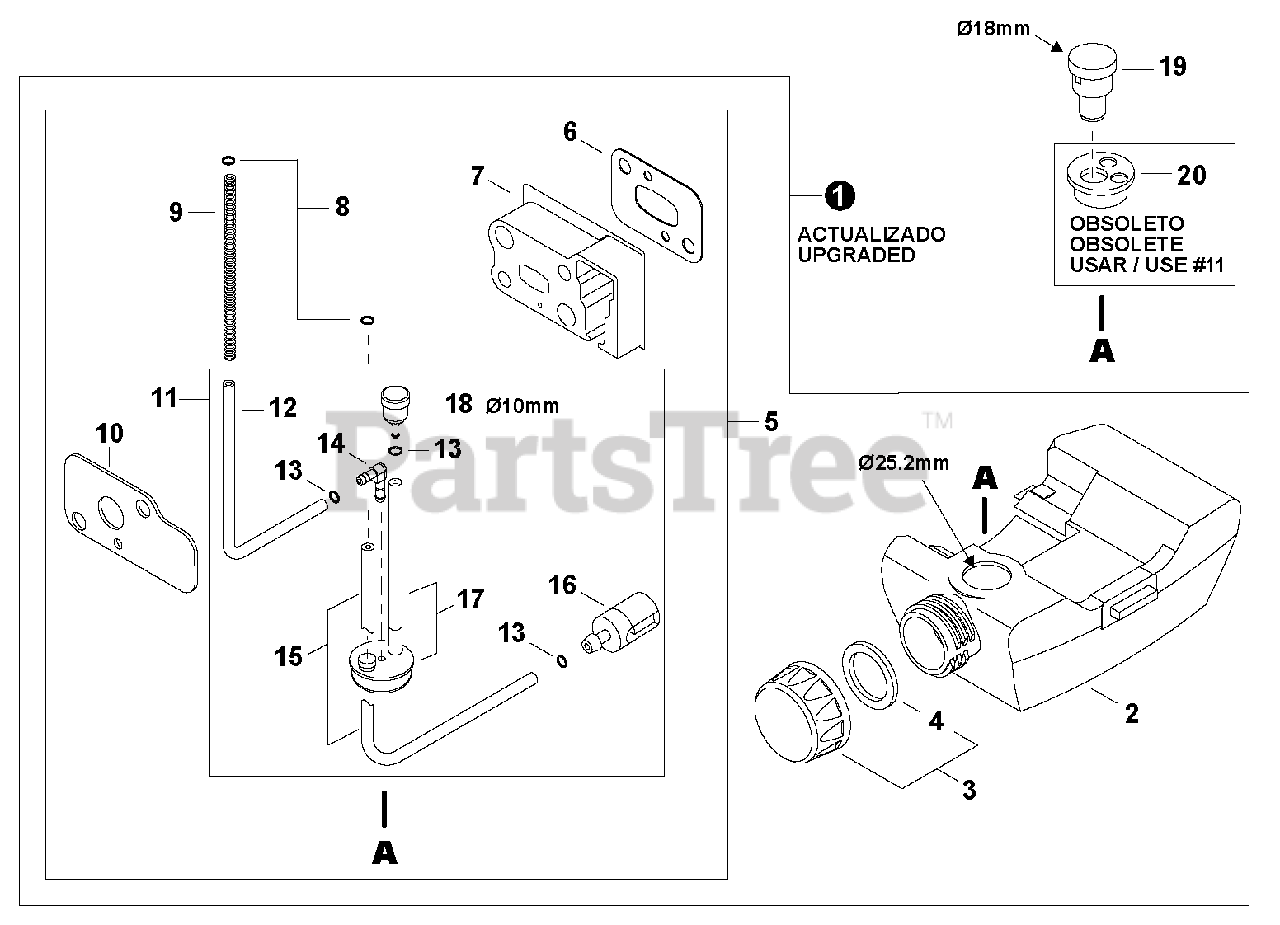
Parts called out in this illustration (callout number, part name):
1	TANK KIT, FUEL
2	TANK, FUEL
3	CAP ASSY, FUEL
4	GASKET, FUEL CAP
5	FUEL PIPE KIT W/GASKETS
6	GASKET, INTAKE
7	INSULATOR
8	CLIP Ø6
10	GASKET, CARBURETOR
11	PIPE KIT, FUEL
12	PIPE, FUEL RETURN
13	CLIP Ø6
14	CONNECTOR, PIPE
15	PIPE, FUEL
16	FILTER, FUEL
17	GROMMET, FUEL
18	VENT ASSY
19	VENT ASSY
20	PIPE KIT, FUEL
